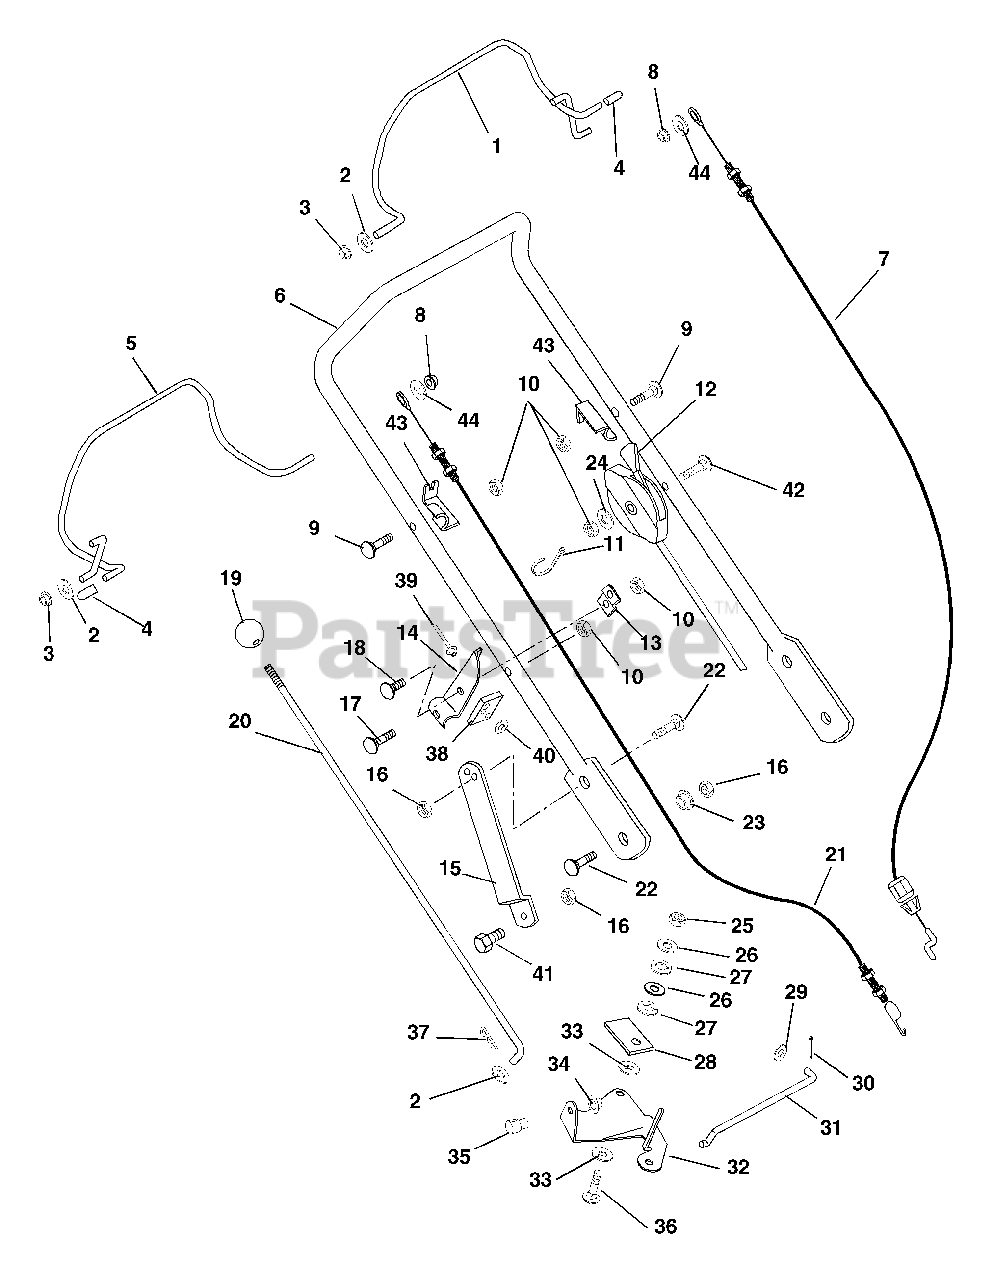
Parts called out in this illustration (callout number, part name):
1	Engine Bail Weldment
2	Washer-Flat-Steel .32 x .44 x .44 x .56
3	Bushing-Flange .325 x .688 x .56
4	Cap, Vinyl .25 I.D.
5	Traction Bail Weldment
6	Handlebar
7	Cable, Briggs and Stratton Engine
8	Push Nut, .25
9	Bolt-Round Head Square Neck .25-20 x 1.25
10	Nut-Locking-Center .25-20
11	Cable Tie
12	Control, Throttle - Intek Pro
13	Brace-Speed Control
14	Bracket-Speed Control
15	Handlebar Bracket
16	Nut-Locking-Center .31-18
17	Bolt-Round Head Square Neck .25-20 x 1.38
18	Bolt-Round Head Square Neck .25-20 x .50 Grade 5
20	Rod-Speed Control
21	Traction Cable
22	Bolt-Round Head Square Neck .31-18 x 1.00 Grade 5
23	Shoulder Spacer
24	Washer-Flat-Steel .250 x .562 x .049
25	Nut-Locking-Center .38-16
26	Washer-Flat-Steel .406 x .812 x .065
27	Washer-Lock .375 x .115 Heavy
28	Pressure Flange
29	Washer-Flat-Steel .281 x .620 x .065
30	Pin-Cotter .06 x .50
31	Shift Link
32	Bell Crank-Speed Control
33	Friction Washer
34	Cap, Rod .375
36	Bolt-Round Head Square Neck .38-16 x 1.25
37	Pin-Hair-Internal .08 x .18 x 1.18
38	Support Pad
39	Rivet .187 x .575
40	Washer-Flat Steel .219 x .50 x .049
41	Bolt-Hex .31-18 x .75 Grade 5
42	Bolt-Round Head Square Neck .25-20 x 1.75 Grade 5
43	Cable Anchor-Left Hand
44	Washer-Flat-Steel .28 x .62 x .065
